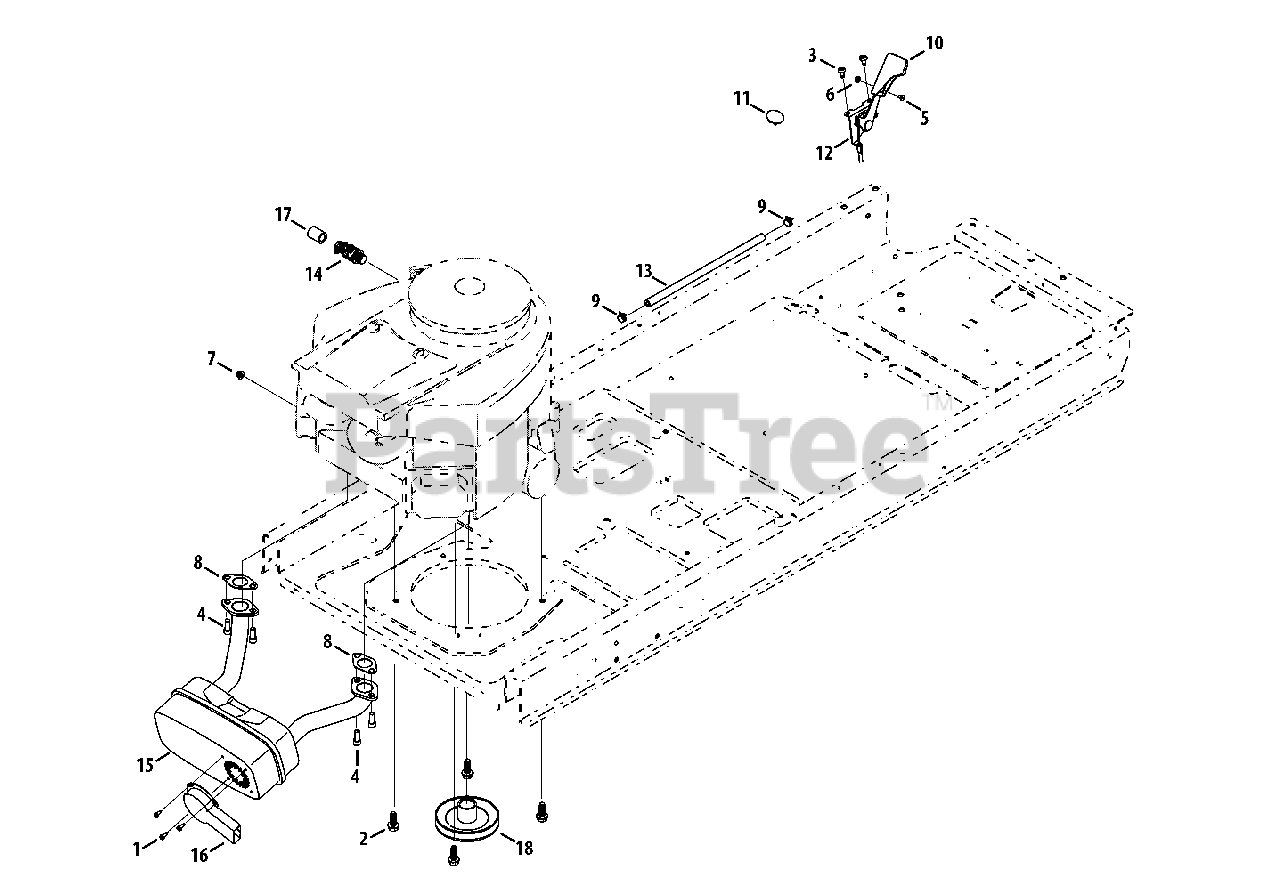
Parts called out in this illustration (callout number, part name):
1	Hex Washer Screw, #8-18 x .500
2	Hex Washer Screw, 3/8-16 x 1.00
3	Screw, 1/4-20 x .50
4	Socket Head Screw, 5/16-18 x .750
5	Screw, #8-32 x .375
6	Hex Nut, #8-32
7	Flange Lock Nut, 1/4-20
8	Exhaust Gasket
9	Hose Clamp, .490 Dia.
10	Throttle Control Knob
11	Choke Plug
12	Throttle/Choke Control Cable
13	Fuel Hose, 1/4
15	Muffler, Intek Twin
16	Muffler Deflector Long
17	Oil Drain Hose
18	Engine Pulley
